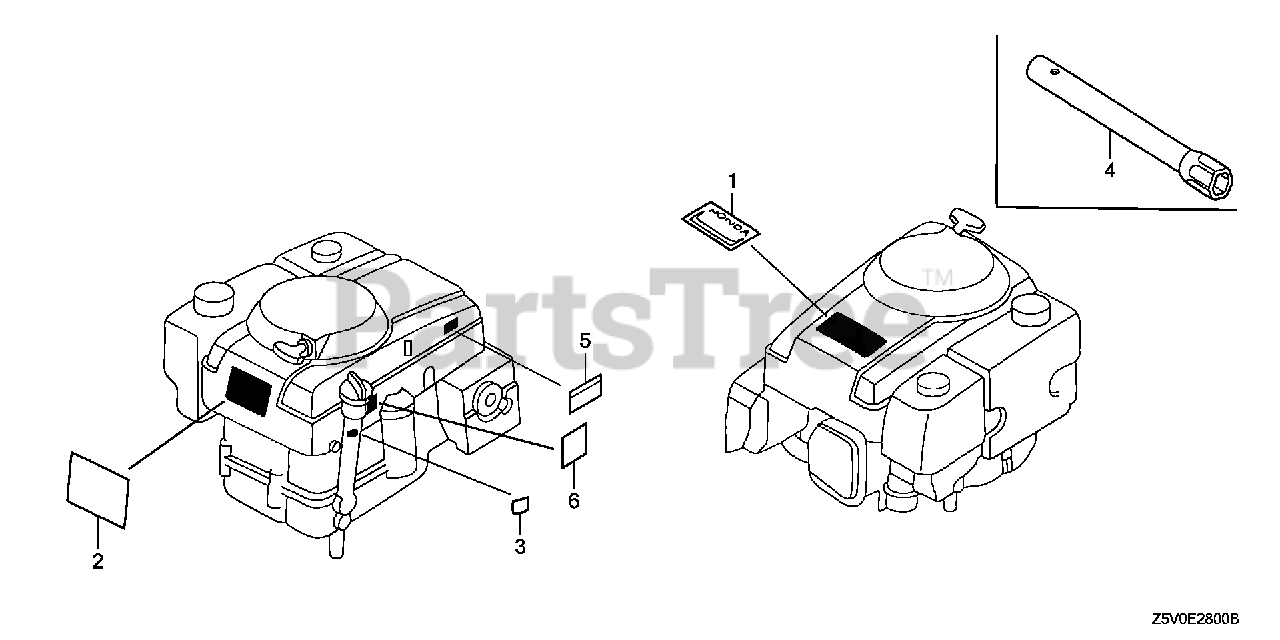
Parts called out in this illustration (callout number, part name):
1	EMBLEM, TOP COVER (GXV390)
2	MARK, OPERATOR CAUTION (ENGLISH)(MADE IN THAI)
2	MARK, OPERATOR CAUTION (PICTOGRAPH)(MADE IN THAI)
3	MARK, TYPE (DA33)
4	WRENCH, BOX (P21)
5	MARK, EX. CAUTION (ENGLISH)
